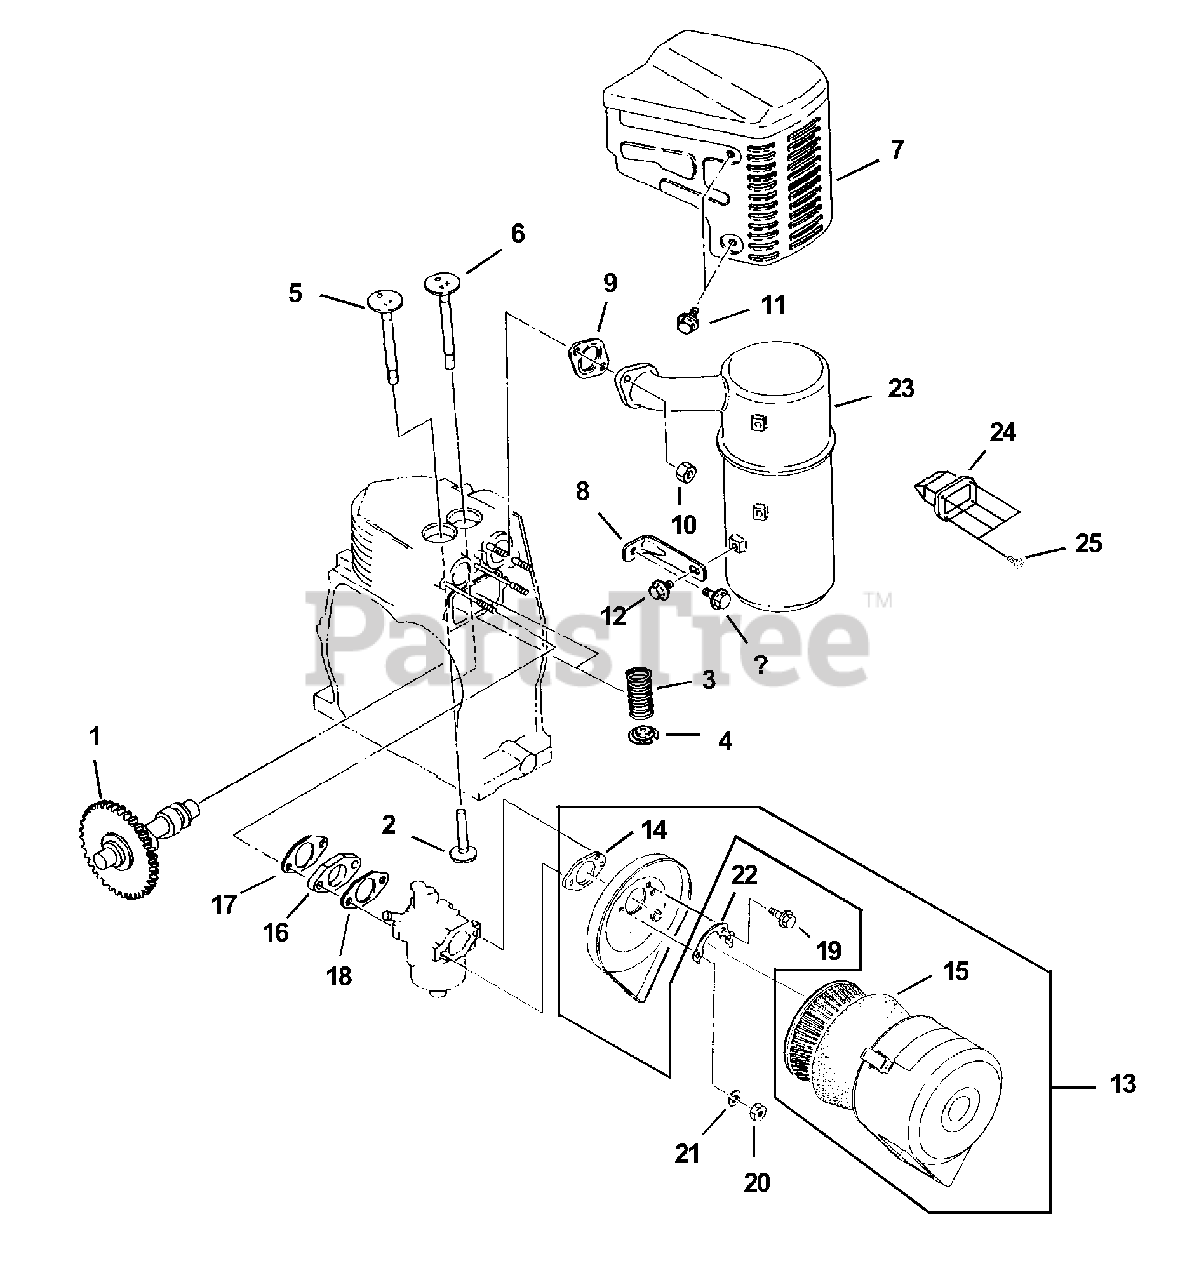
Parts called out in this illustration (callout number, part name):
1	Camshaft
3	Valve spring
4	Spring retainer
5	Intake valve
6	Exhaust valve
7	Muffler cover
8	Muffler bracket
9	Muffler gasket
10	Nut (M8 X 1.25)
11	Flange bolt (M6 X 1.0 X 8L)
12	Flange bolt (M6 X 1.0 X 12L)
13	Air filter assy
14	Gasket air filter
15	Air filter
16	Insulator
17	Insulator gasket
18	Insulator gasket
19	Bolt & washer (M6 X 1.0 X 12L)
20	Nut (M6 X 1.0)
21	Spring washer
22	Lock washer
24	Spark Arrestor
25	Screw, Tapping (M4 X 0.7 X 8L)
